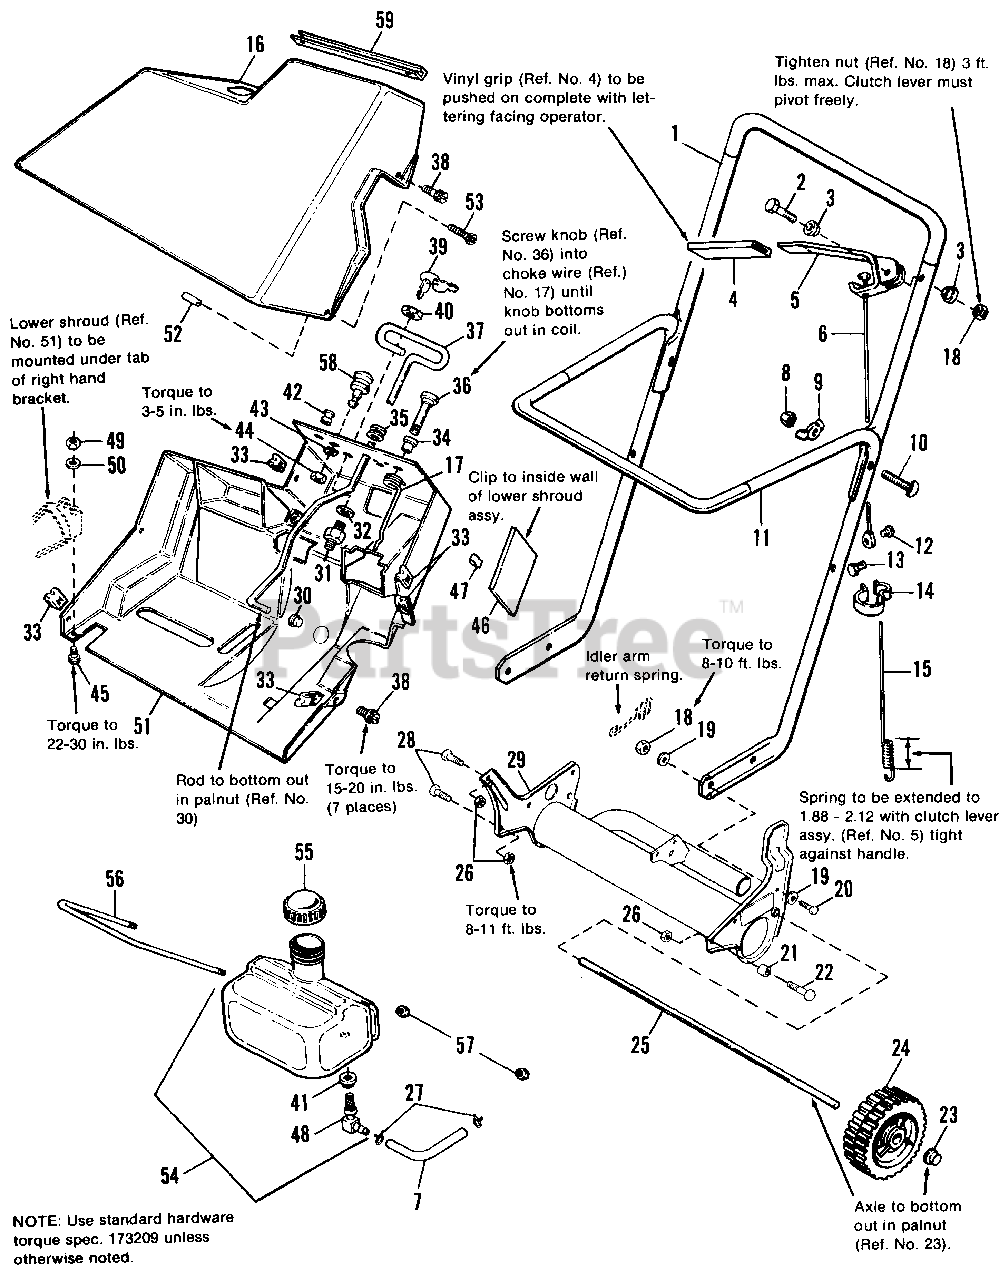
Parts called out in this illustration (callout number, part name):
1	HANDLE, Upper
2	CAPSCREW, Hex Hd., 1/4-20 x 1-3/4
4	GRIP, Handle
5	LEVER ASSY., Clutch
6	CABLE ASSY., Clutch Control
7	HOSE, Fuel
8	NUT, Acorn, 5/16-18
9	NUT, Wing
10	BOLT, Curved Hd.
11	HANDLE, Lift
12	SCREW, Round Hd., #8-32 x 5/16
15	SPRING, Tension
16	SHROUD, Upper
17	WIRE, Choke Control
18	LOCKNUT, Plain, 1/4
19	WASHER, Plain, 1/4
20	CAPSCREW, Hex Hd., 1/4-20 x 7/8
21	SPACER, L.H.
22	CAPSCREW, Hex Hd., 5/16-18 x 1-1/2
23	PUSHNUT, 3/8
26	LOCKNUT, Hex, 5/16-18
27	HOSE, Clamp
28	CAPSCREW, Hex Hd., 5/16-18 x 3/4
30	PUSHNUT, 1/4
31	SWITCH, Ignition
32	LOCKWASHER, Int. Tooth, 5/8
33	NUT, Speed, "U", #10
34	GUIDE, Choke Knob
36	KNOB, Choke Control
37	ROD, Vane Control
38	SCREW, Hex Wash. Hd., Slotted, #10-14 x 5/8
39	KEY & RING ASSY., (2 Keys)
40	NUT, Ignition Switch
42	GUIDE, Starter Rope
43	LOCKWASHER, Ext. Tooth, 1/4
44	NUT, Hex, Jam, 1/4-20
45	SCREW, Hex Wash. Hd., Slotted, #10-24 x 5/8
46	HEAT SHIELD
47	CLIP, Tinnerman
48	FITTING, Fuel Tank
49	LOCKNUT, Center, #10-24
50	WASHER, Plain, #10
51	SHROUD, Lower
53	SCREW, Plastite, #10-14 x 1-3/4
54	TANK ASSY., Fuel
56	CLAMP, Tank
57	NUT, Hexlock, Nylon #8-32
58	BULB, Primer
59	CHANNEL, Trim
